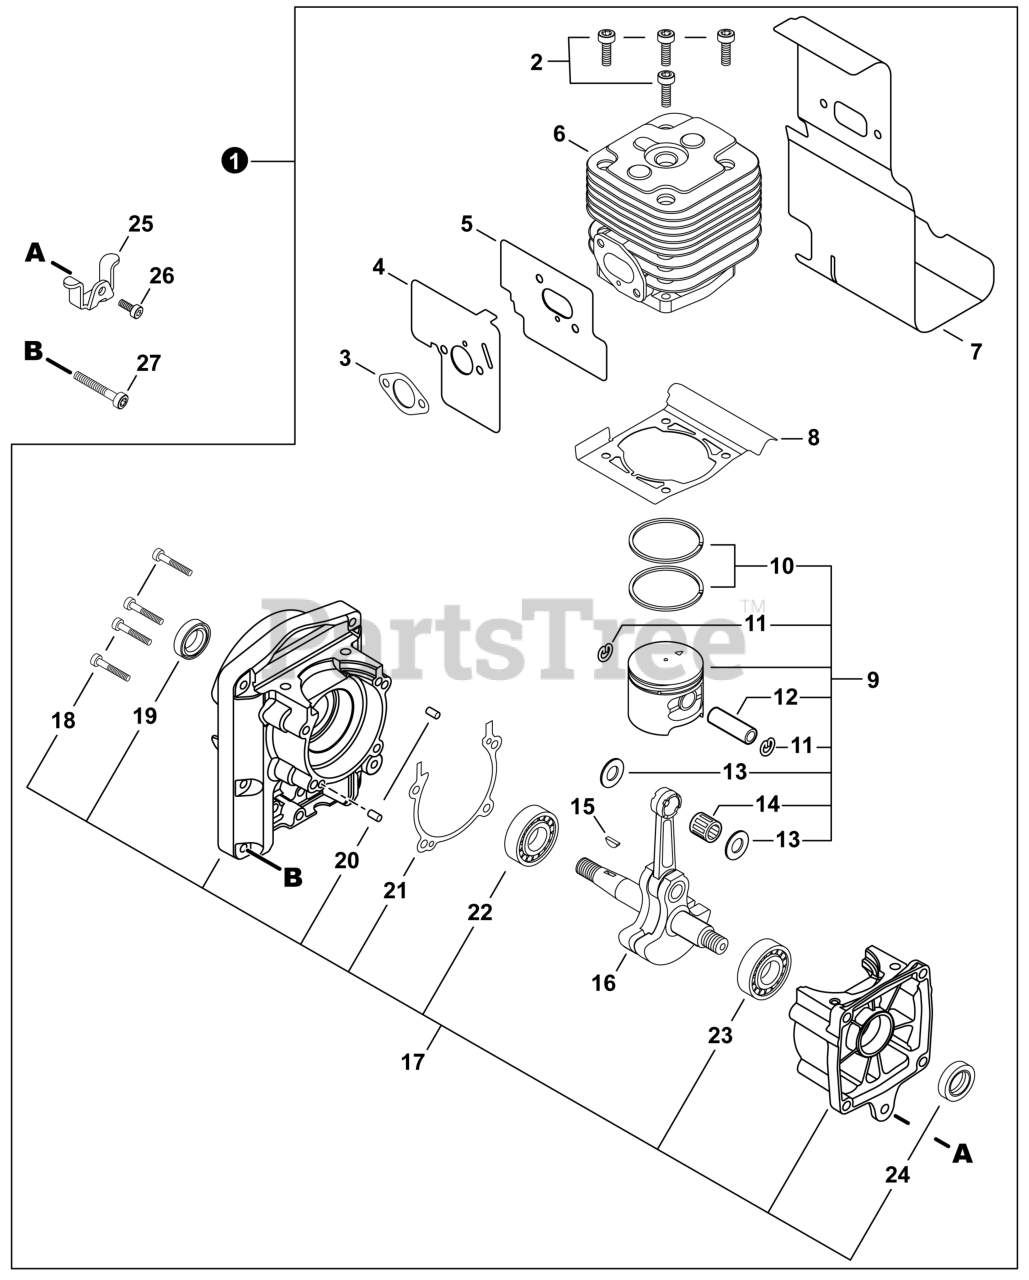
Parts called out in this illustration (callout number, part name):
1	SHORT BLOCK
2	BOLT, TORX 5×20
3	GASKET, INTAKE
4	GASKET, INTAKE
5	HEAT SHIELD, INTAKE
6	CYLINDER
7	HEAT SHIELD, EXHAUST
8	GASKET, CYLINDER
9	PISTON KIT
10	RING, PISTON
11	RING, SNAP Ø10
12	PIN, PISTON 10
13	WASHER, THRUST 10
14	BEARING, NEEDLE 10
15	KEY, WOODRUFF 3×14
16	CRANKSHAFT
17	CRANKCASE KIT
18	BOLT, TORX 5×30
19	SEAL, OIL
20	PIN, LOCATING 4×8
21	GASKET, CRANKCASE
22	BEARING, BALL 6302 C3
23	BEARING, BALL 6202
24	SEAL, OIL 15
25	CUSHION 5
26	BOLT, TORX 5×12
27	BOLT, TORX 5×30
